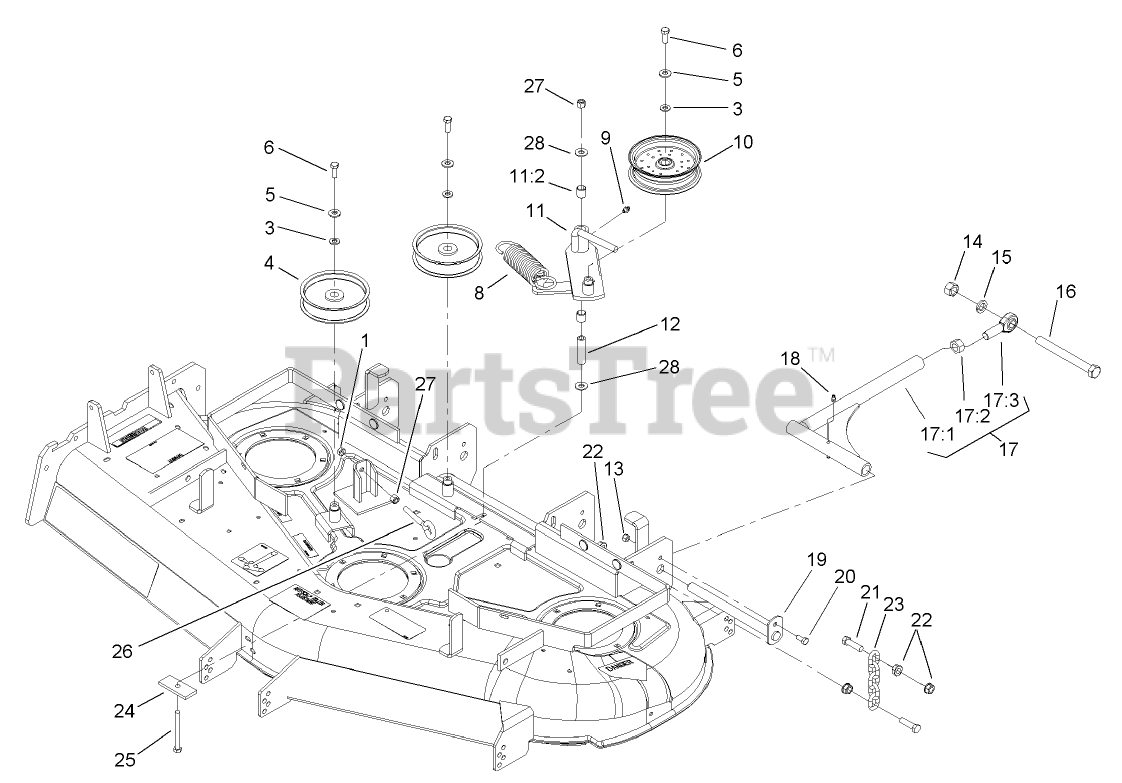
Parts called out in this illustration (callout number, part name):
1	NUT-HEX
3	WASHER-FLAT
4	PULLEY-IDLER
5	WASHER-BELLEVILLE
6	SCREW-HH
8	Spring-Extension
9	FITTING-GREASE, 90 DEG
10	PULLEY-IDLER, FLAT
11	IDLER ARM ASM
11:2	SLEEVE-BEARING
12	BUSHING-PIVOT, IDLER
13	NUT-LOCK, NI
14	NUT-HEX
15	WASHER-LOCK
17	STRUT ASM
17:1	STRUT
17:2	NUT-HEX
17:3	BALLJOINT-SPHERICAL
18	FITTING-GREASE
19	PIN-STRUT
20	SCREW-HH
21	SCREW-CAP, HH
22	NUT-HF
23	CHAIN-LIFT, DECK
24	PLATE-RETAINER, BOLT
25	SCREW-HH
26	BOLT-EYE
27	NUT-LOCK, NI
28	WASHER-HARDENED
